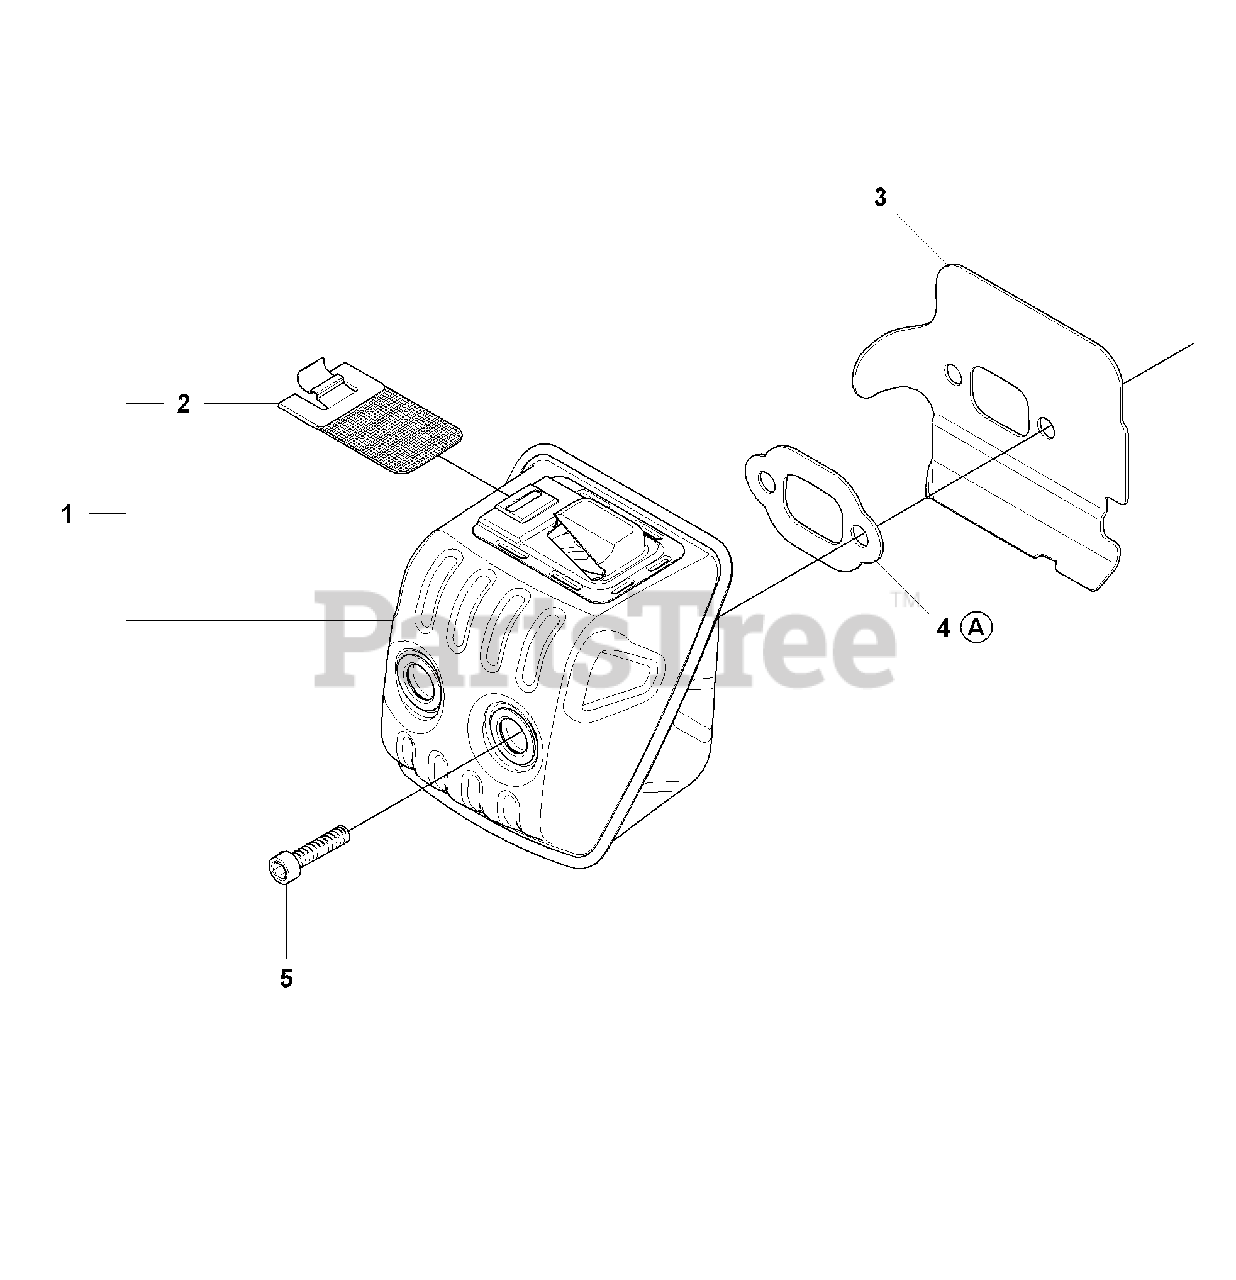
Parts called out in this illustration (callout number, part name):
1	%MUFFLER ASSY
2	SPARK ARRESTER
3	%HEAT DEFLECTOR
4	RP GASKET
5	SCREW MC6S 6X16
